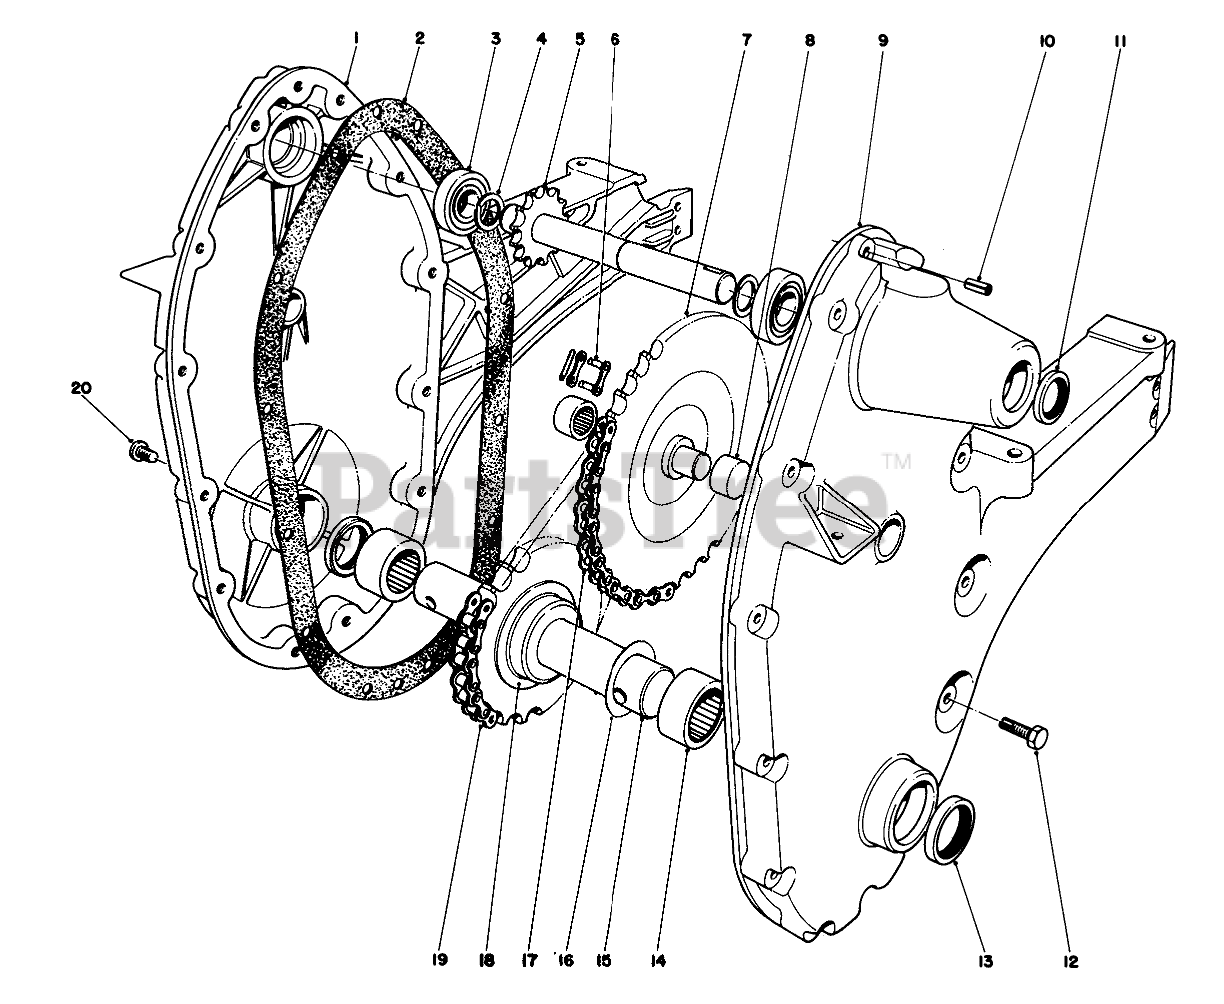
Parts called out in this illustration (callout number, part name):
1	Chain Case R H.
2	GASKET TILLER
3	BALL BRG
4	5/8X030 EX MED RING
5	Upper Shaft
6	LINK-CONNECTING, NO. 35
7	Sprocket Cluster
8	NEEDLE BRG
9	Chain Case L.H.
10	PIN-ROLL
11	SEAL-OIL
12	SCREW-HWH, TAP
13	SEAL-OIL
14	NEEDLE BRG
15	TINE SHAFT
16	Washer
17	Roller Chain
18	Cup Spacer
19	Roller Chain
